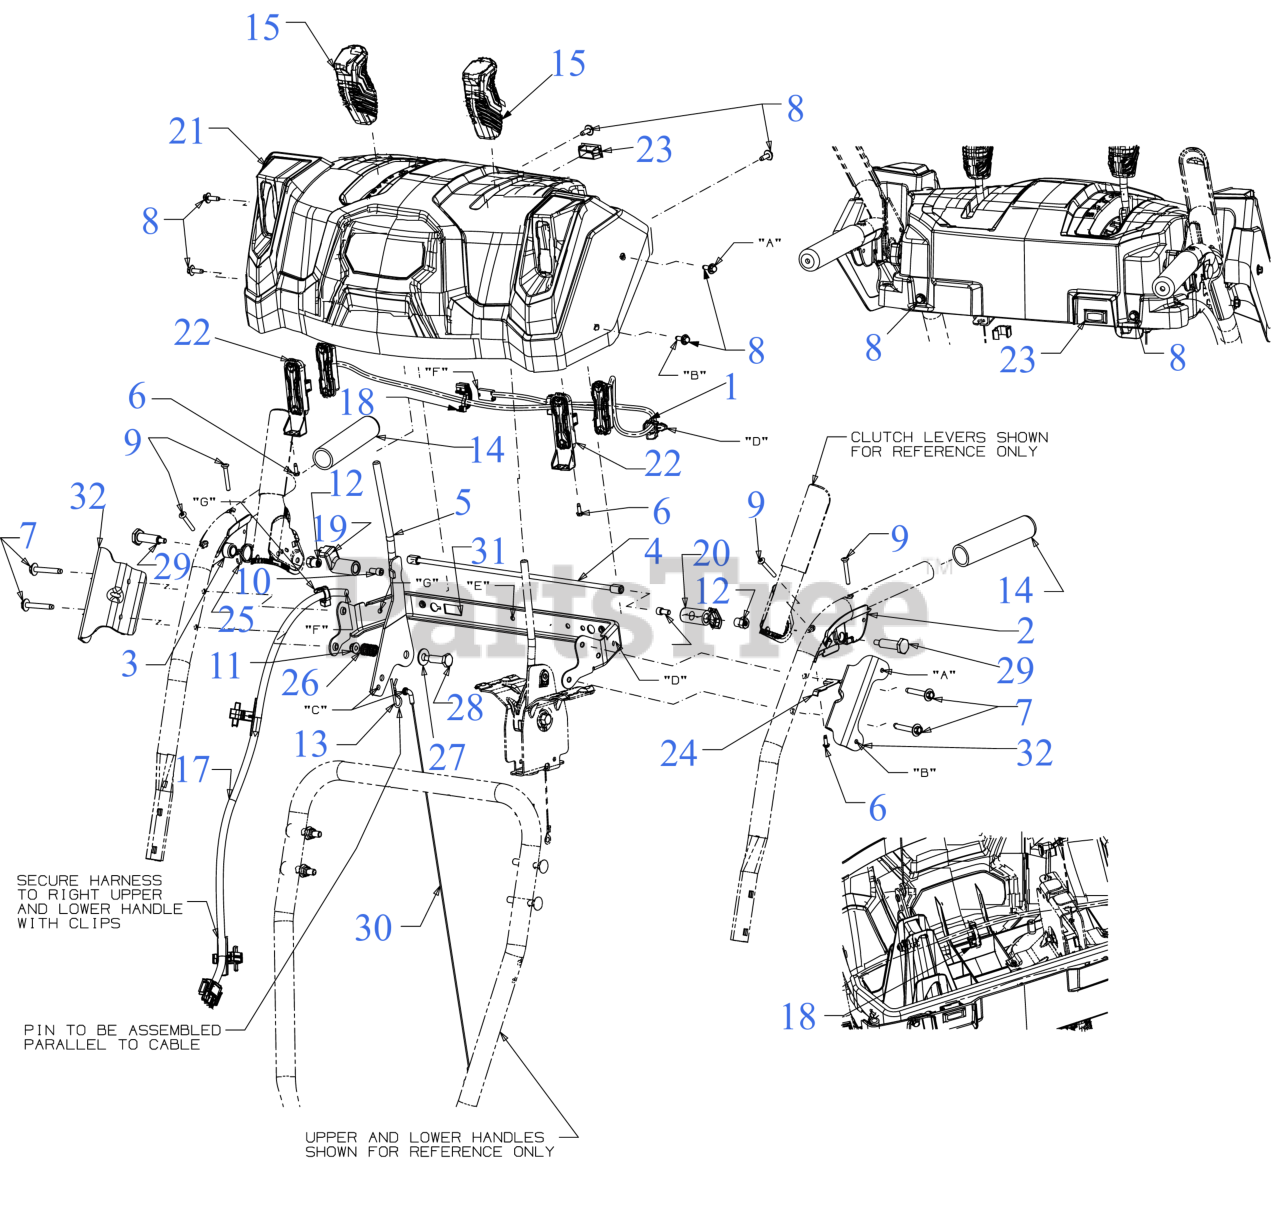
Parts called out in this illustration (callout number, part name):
1	HEADLIGHT HARNESS (W/LED)
2	CLUTCH LOCK HANDLE ASSEMBLY (LH)
3	CLUTCH LOCK HANDLE ASSEMBLY (RH)
4	PIVOT ROD
6	SCREW #8-16 x .50
7	SCREW 1/4-20 x 1.625
8	SCREW M6-1 x .625
9	SCREW #10-24 x 1.375
10	SCREW 1/4-20 x .50
11	FLANGE LOCK NUT
12	HEX NUT W/PATCH
13	INTERNAL COTTER PIN
17	LED HEADLIGHT HARNESS
18	EDGE MOUNT ZIP TIE CLIP
19	LOCK PLATE
20	CLUTCH LOCK CAM
21	HANDLE PANEL
22	LENS BEZEL
23	SWITCH PLUG
24	CLUTCH SPRING
25	TORSION SPRING
26	COMPRESSION SPRING
27	FLAT WASHER
28	SHOULDER SCREW
29	SHOULDER SCREW .437 x 1.345 1/4-20
30	SPEED SELECTOR CABLE (PLASTIC)
